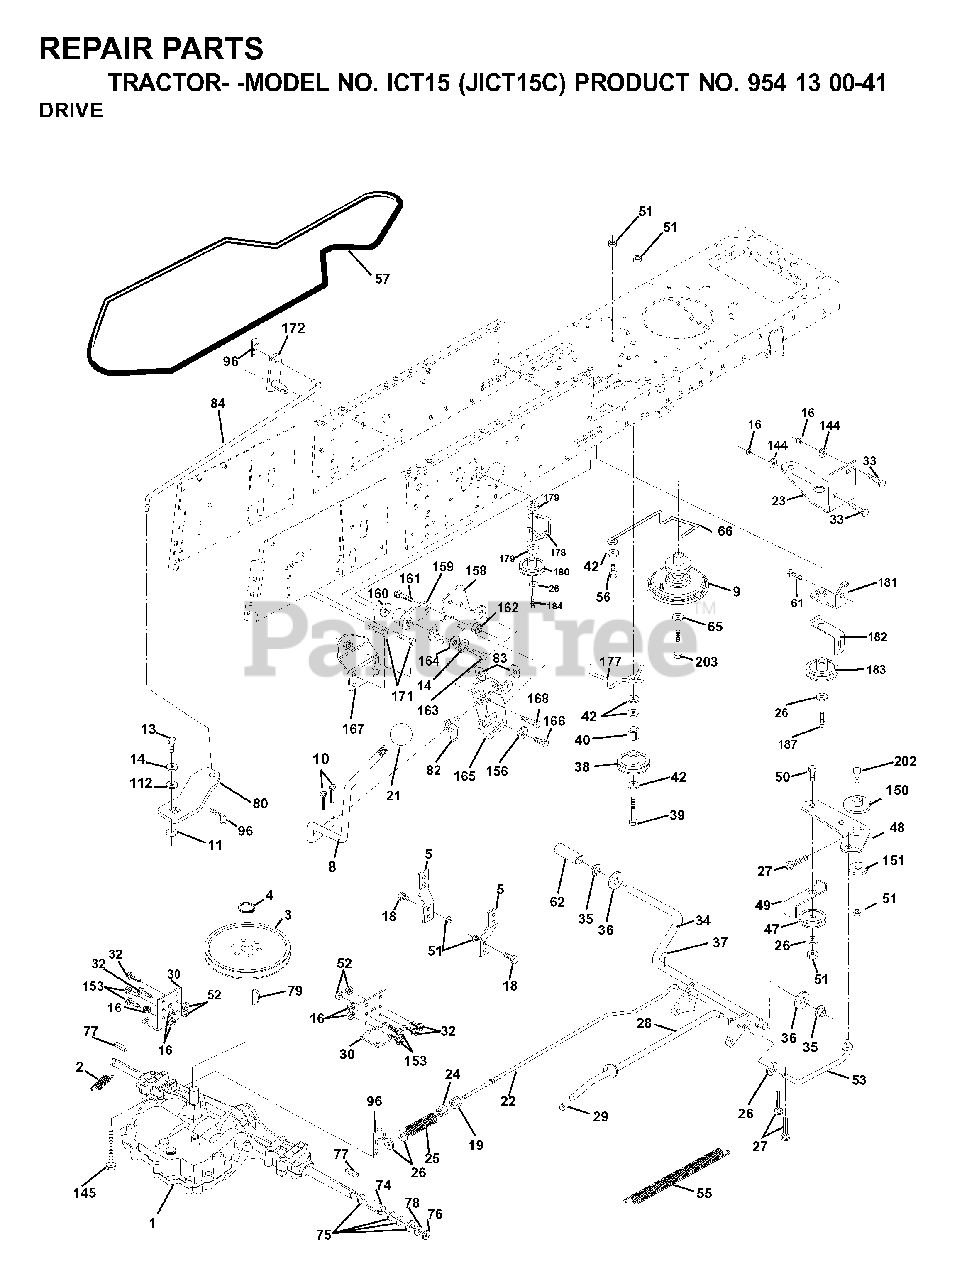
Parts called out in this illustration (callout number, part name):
2	SPRING,BRAKE RETURN
4	RETAINING RING LT
5	STRAP TORQUE
8	ROD SHIFT
9	CLUTCH ASSY
10	PIN COTTER
11	WASH-SHFT PLT LT
13	BOLT 1/4-28X3/4
14	LOCKWASHER
16	NUT.71038.31-18.HEX.NYLOCK
19	NUT
21	PISTOL KNOB
24	NUT
25	SPRING ROD LT
27	COTTER PIN
28	ROD BRAKE PARK LT
29	PLUNGER CAP
30	BRACKET TRANSAXLE
32	BOLT
33	BOLT
35	BEARING.NYLON
36	WASHER LT
37	DRIVE PIN
38	PULLEY.FLAT
42	WASHER
47	IDLER PULLEY
48	BELLCRANK, CLUTCH
49	RETAIN BELT
50	BOLT
51	LOCKNUT
52	LOCKNUT
53	LINK, CLUTCH LT
55	SPRING, RETURN LT
61	SCREW 3/8-16X3/4
62	PEDAL COVER T
65	LOCKWASHER
66	KEEPER BELT ENGINE
74	SPACER AXLE
76	E-RING LT
77	SQUARE KEY
80	ARM SHIFT
82	SPRING,TORSION
83	WASHER
96	RETAINER M
112	WASHER LT
144	WASHER
150	BUSHING.BELLCRANK.GRD.DR
151	WASHER 12/32X2X10GA
153	BOLT RB
156	WASHER.SRRTD.5/16
158	BRACKET
159	HUB
161	BOLT
162	NUT.CROWNLOCK.1/4
165	RP BRACKET
167	BRACKET
168	BOLT.SHOULDER.5/16-18X
180	PULLEY.FLAT.IDLER
182	KEEPER BELT
183	PULLEY.V-IDLER
184	SCREW.HXWSH.3/8
187	SCREW
188	SNAP BUSHING T
198	WASHER.NYL.7/8IDX.105"HYD CR
202	BOLT.3/8-16X1.50
